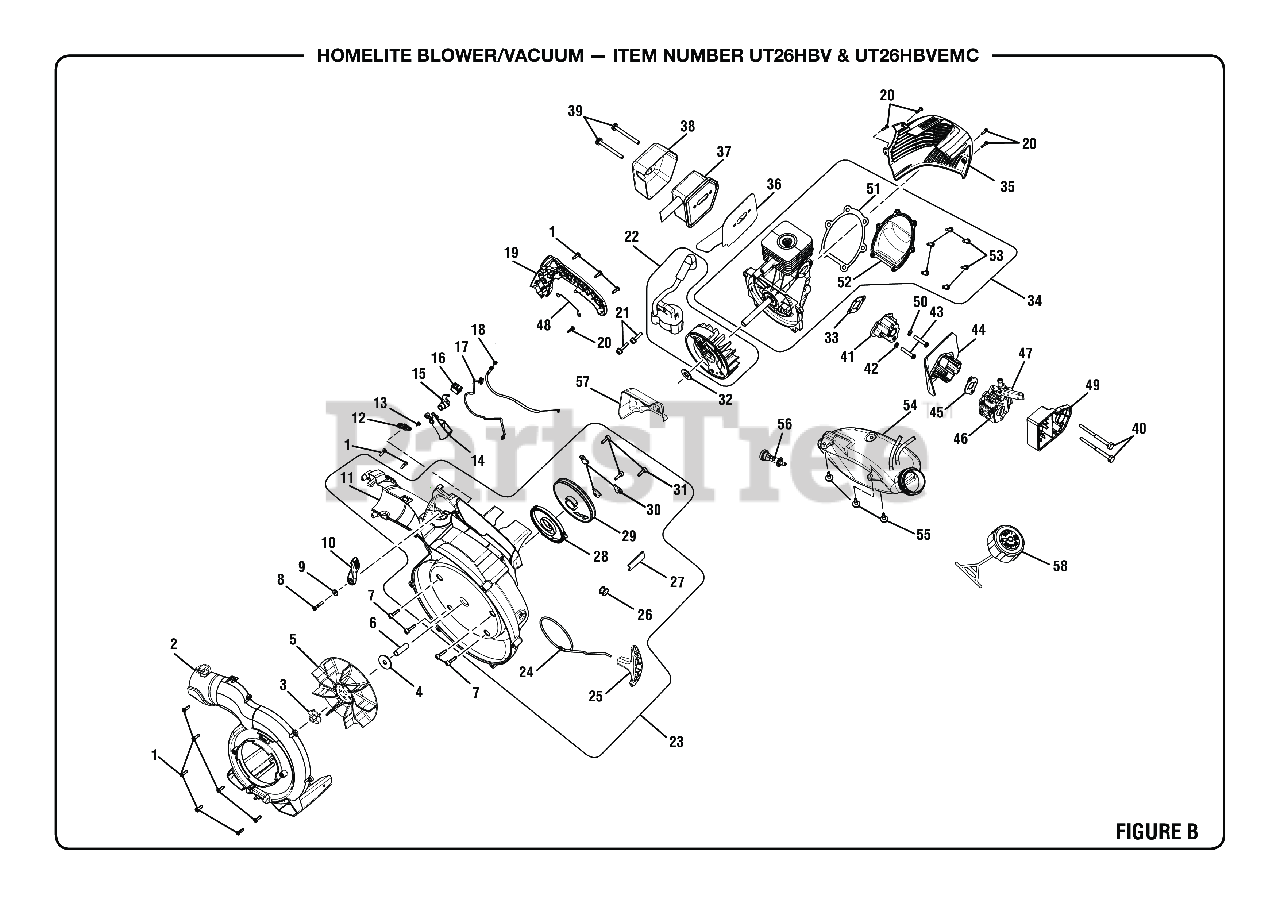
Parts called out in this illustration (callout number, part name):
1	Screw (#10-14 x 3/4 in, T25 Torx Pan Hd. T.F.)
2	Outer Volute w/Labels
3	Lock Nut (3/8 in.)
4	Washer (ID9.8 x OD30 x 3t)
7	Screw w/Washer (M4 x 16 mm, T25 Torx Truss Hd.)
8	Cruise Lever Screw (M8-14 x 25 mm, Special T20 Truss Hd.)
9	Washer (ID 4.3 x OD12 x 1.5t)
10	Cruise Control Lever
11	Inner Volute w/Eyelet w/Label
12	Throttle Lever
13	Screw (M3.5 x 7.5 mm, T20 Torx Pan Hd.)
14	Throttle Trigger
15	Trigger Lock
16	Stop Switch (Momentary Contact)
17	Wire Assembly (UT26HBV)
18	Throttle Cable
19	Handle Cover
20	Screw (M4 x 18 mm, T20 Torx Pan Hd. S.T.)
21	Screw w/Washer (M4 x 19 mm, T20 Torx Pan Hd. S.T.)
22	Ignition Module and Flywheel Kit (UT26HBV)
23	Lower Housing w/Starter and Label
24	Starter Rope (42 in.)
25	Pulley Handle
28	Spring & Container Assembly
29	Starter Pulley
30	Pulley Retainer
31	Screw (M4 x 14 mm, T20 Torx Truss Hd T.F.)
32	Washer (ID9.70 x OD20 x 1.59t)
33	Intake Gasket
34	Short Block Assembly
35	Engine Cover w/Labels
36	Muffler Gasket
37	Muffler Assembly
38	Muffler Heat Shield
39	Screw w/Washers (10-24 x 2-1/8 in., T25 Torx Truss Hd.)
40	Bolt (M5 x 48 mm, T20 Torx hd.)
42	Washer (ID5 x OD10.9 x 0.5t)
43	Screw (M5 x 25 mm, T20 Torx Hd.)
45	Heat Dam Gasket
46	Carburetor
47	Primer Bulb (Ruixing)
48	Ground Wire Assembly
49	Air Box Base
51	Crankcase Cover Gasket
52	Crankcase Cover
53	Screw (M4 x 12 mm, T20 Torx Hd.)
54	Fuel Tank Assembly (Inc. Fuel Lines)
55	Shoulder Screw w/Washer (M4 x 14 mm, T25 Torx Truss Hd.)
56	Fuel Filter
57	Baffle Plate
58	Fuel Cap Assembly (Inc. Tether)
